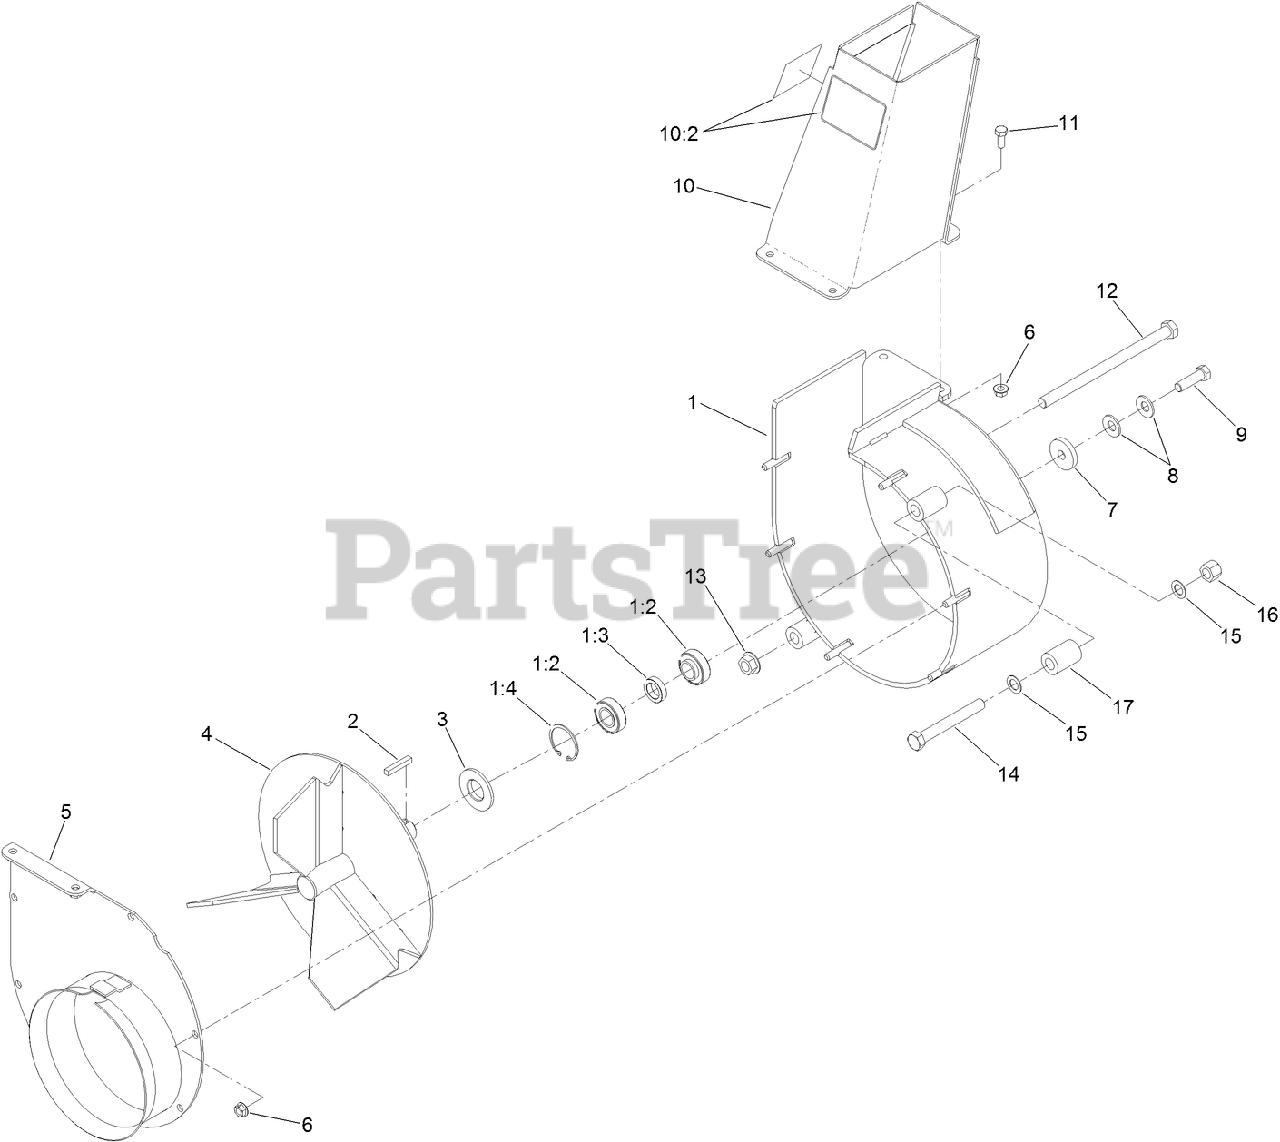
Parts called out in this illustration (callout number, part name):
1	HOUSING ASM
1:2	Bearing-Ball
1:3	Spacer-Bearing
1:4	RING-SNAP
2	KEY-SQUARE
3	Spacer-Blower
4	IMPELLER-3 BLADE
5	COVER-BLOWER
6	NUT-HF
7	WASHER-CLUTCH
8	WASHER-SPRING
9	SCREW-HH
10	DISCHARGE CHUTE ASM
10:2	DECAL-DANGER, IMPELLER
11	SCREW-HH
12	SCREW-HH
13	NUT-HF
14	SCREW-HH
15	WASHER-THRUST
16	NUT-LOCK, NI
17	SPACER-MOUNT
